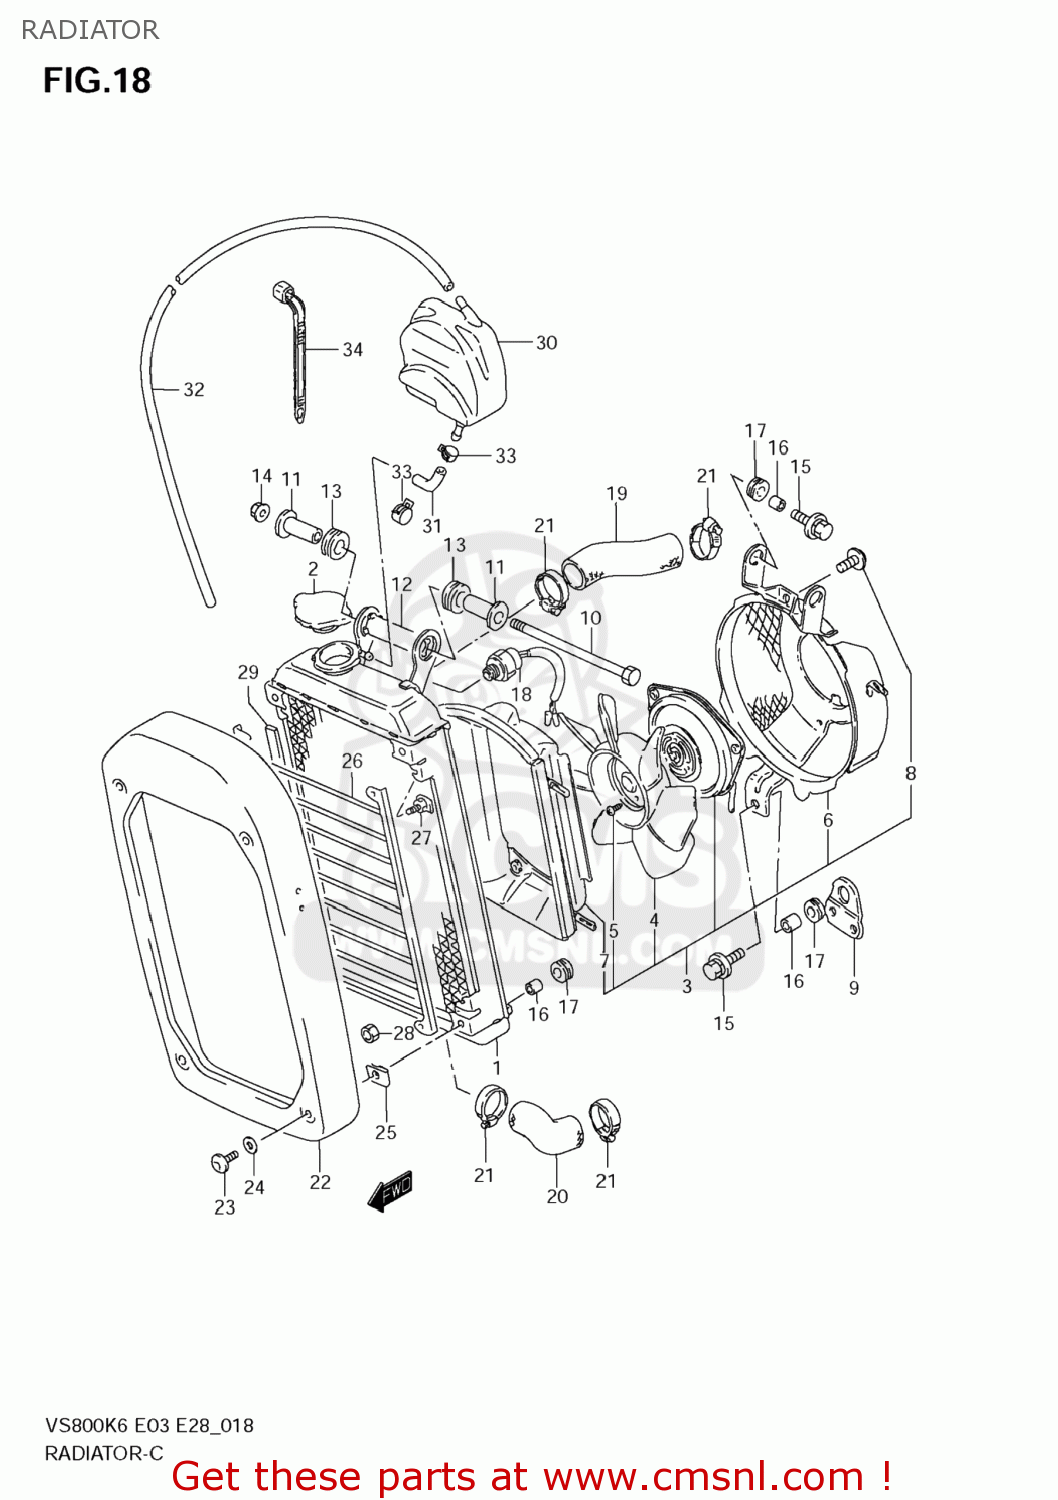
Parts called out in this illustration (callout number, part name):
1	RADIATOR ASSY,WATER
2	CAP COMP,RADIATOR
3	FAN ASSY,RADIATOR
4	FAN
5	SCREW 4X6
6	SHROUD,FAN
7	DUCT,FAN
8	SCREW
9	BRACKET,RADIATOR FAN
10	BOLT(10X135)
11	SPACER,RADIATOR CUSHION NO.2
12	SPACER,RDTR CUSH NO.2 OUTER
13	CUSHION
14	NUT
15	BOLT(6X16)
16	SPACER(6.5X9X8)
17	CUSHION
18	SWITCH,RADIATOR FAN
19	HOSE,RADIATOR INLET
20	HOSE,WATER PUMP OUTLET
21	CLAMP
22	COVER,RADIATOR(SILVER)
23	SCREW(6X10)
24	WASHER(6.5X14X2)
25	NUT
26	BUMPER,RADIATOR
27	BOLT
28	NUT
29	CUSHION,RADIATOR BUMPER
30	TANK,RESERVOIR
31	HOSE,RESERVE TANK INLET
32	HOSE,RESERVOIR TANK OUTLET
33	CLIP
34	CLAMP(L:125)
